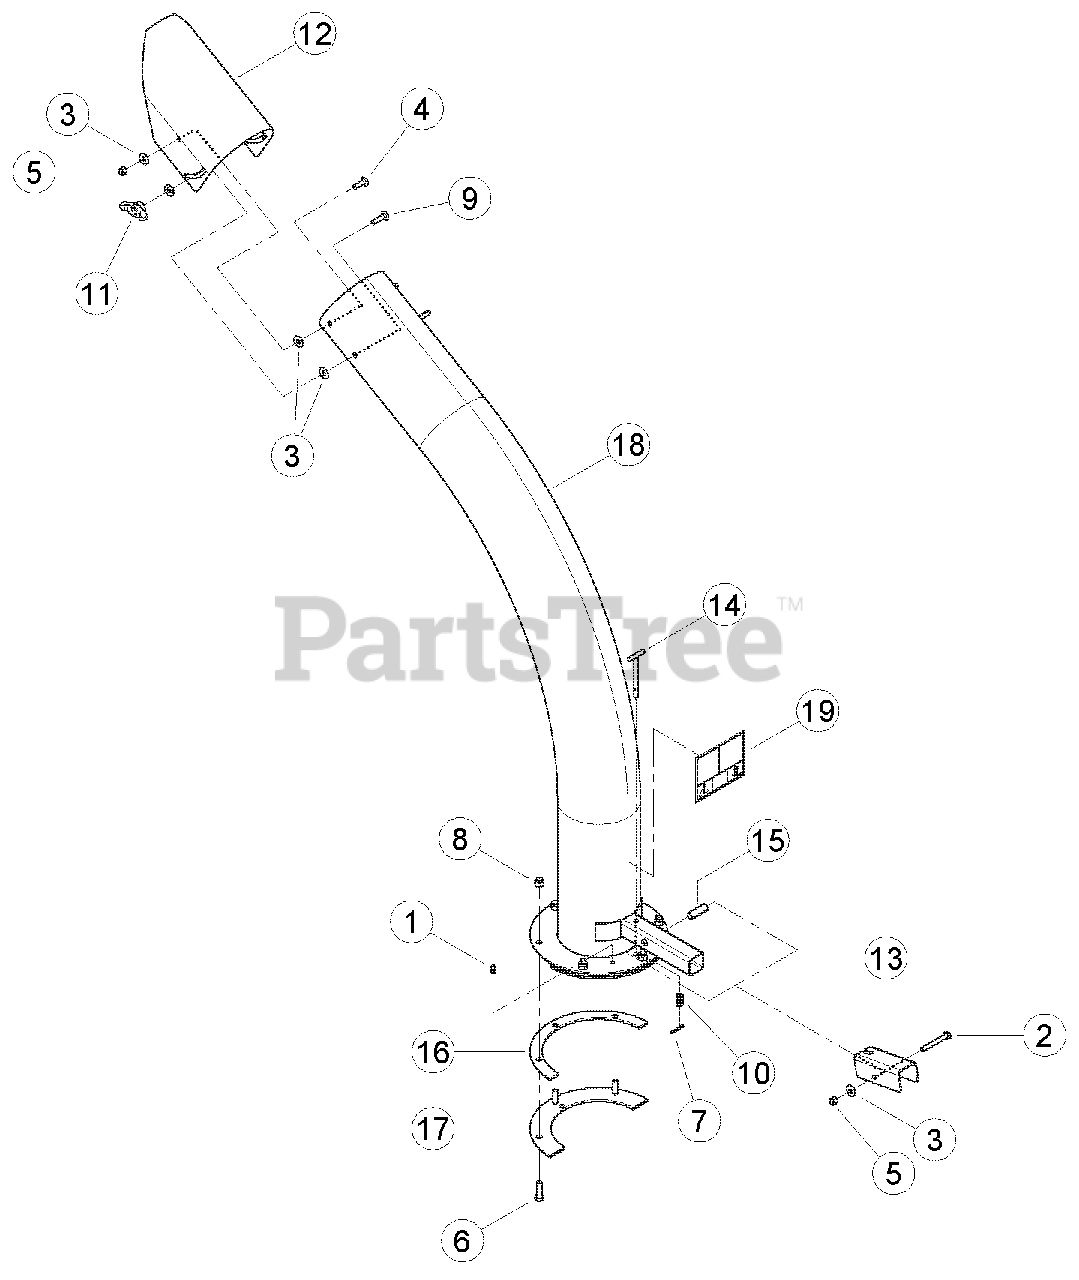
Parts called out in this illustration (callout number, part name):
1	FITTING, 1/4 SELF-TAP GREASE
2	BOLT, 5/16 X 2-1/2 HEX HD GR5 ZP
3	WASHER, 5/16 FLAT ZP
4	BOLT, 5/16 X 1 CRG GR5 ZP
5	NUT, 5/16 NE NYLOCK ZP
6	BOLT, 3/8 X 1-1/4 HEX HD GR5 ZP
7	PIN, 1/8 X 1.00 COTTER ZP
8	NUT, 3/8 NE NYLOCK ZP
9	BOLT, 5/16 X 1-1/4 CRG GR5 ZP
10	SPRING, LOCK COMPRESSION
11	KNOB, 5/16-18 UNC TEE W/LOCKING INSERT
12	DEFLECTOR, BLOWER-VAC DISCHARGE
13	LEVER, DISCHARGE LOCK
14	WELDMENT, DISCHARGE LOCK PIN
15	TUBE, DISCHARGE LOCK PIVOT
16	SPACER, DISCHARGE PIVOT
17	RING, DISCHARGE CLAMP
18	ASSEMBLY, 6 INCH DISCHARGE SERVICE PART
19	DECAL, DISCHARGE DEBRIS & LOCK
